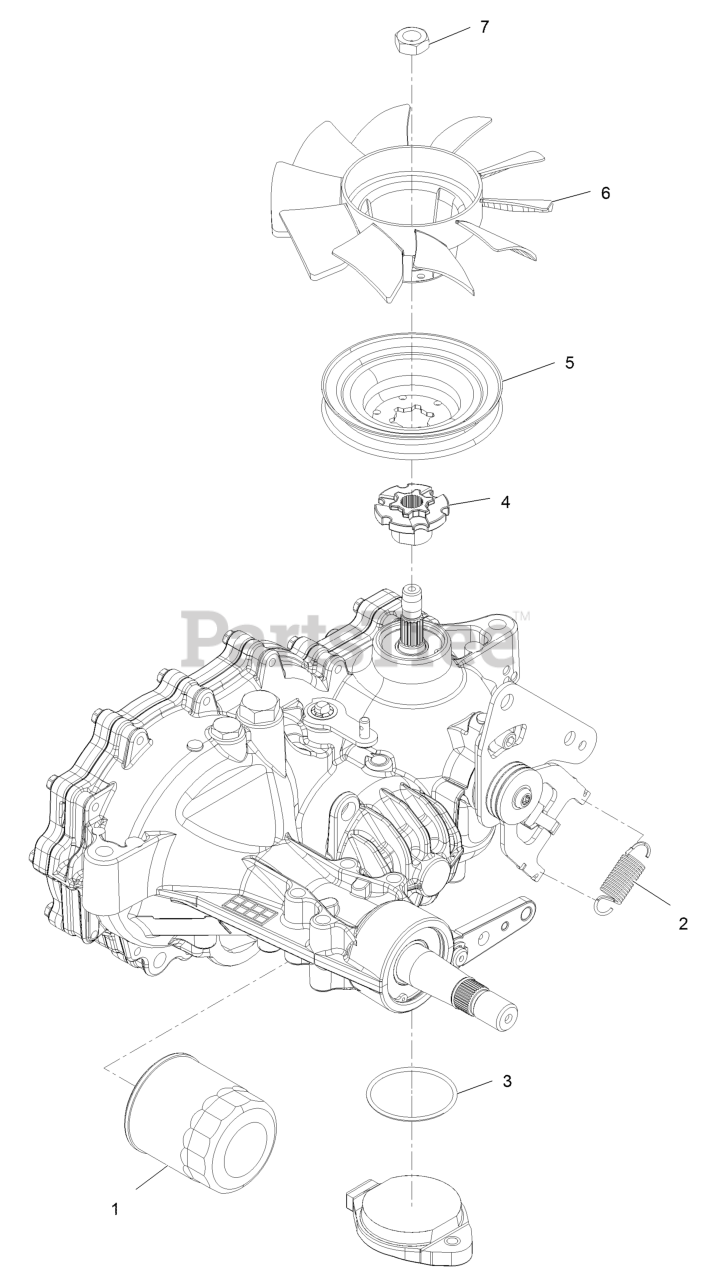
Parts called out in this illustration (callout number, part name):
1	Filter-Hydraulic
2	Spring-Extension Rtn-25 Lbs
3	O-Ring-Charge Seal Cover
4	Hub-Pulley
6	Fan-7.0 (10 Blade)
99	Brake Shaft Seal Kit
